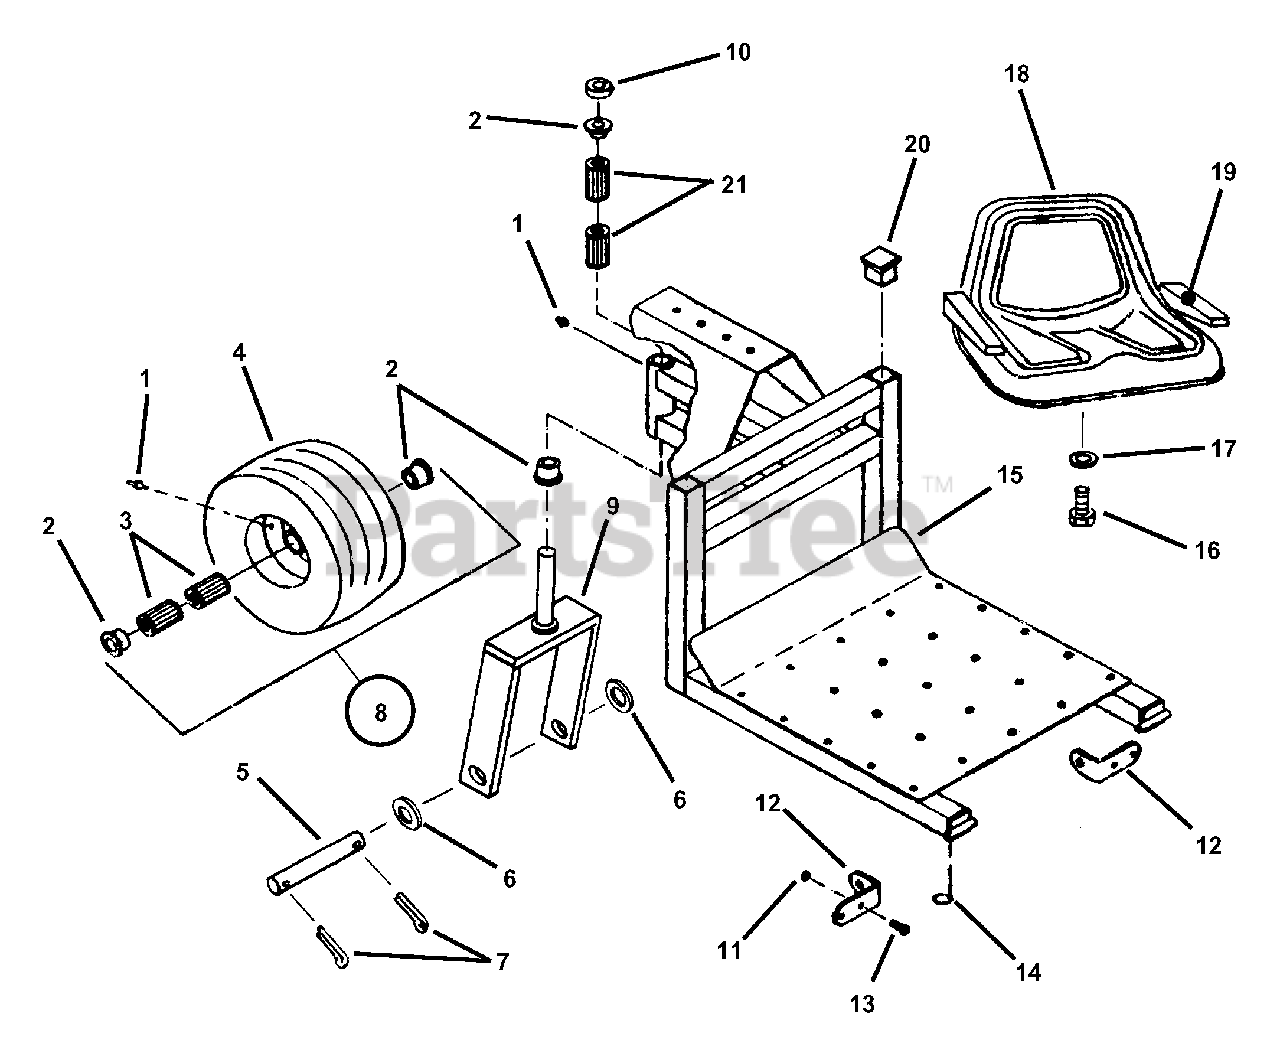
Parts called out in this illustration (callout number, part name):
1	FITTING, 1/4-28 Grease
2	BEARING, Flange
3	BEARING, Roller
4	TIRE, Straight Ribbed w/Rim
5	PIN, Axle
7	PIN, 1/8 x 1-1/2" Cotter
8	ASSEMBLY, Tire
9	WELDMENT, Swivel
10	7/8" CLAMP, Collar
11	NUT, 3/8-16 Hex Nyloc
12	BRACKET, Hitch
13	SCREW, 3/8-16 x 1" Hex Head Cap, Grade 5
14	PIN, 3/16" Dia. Lynch
16	SCREW, 1/2-13 x 3/4" Hex
17	WASHER, 1/2" Split Lock
18	SEAT w/Decal
19	KIT, Arm
20	PLUG, Square
21	BEARING, Roller
